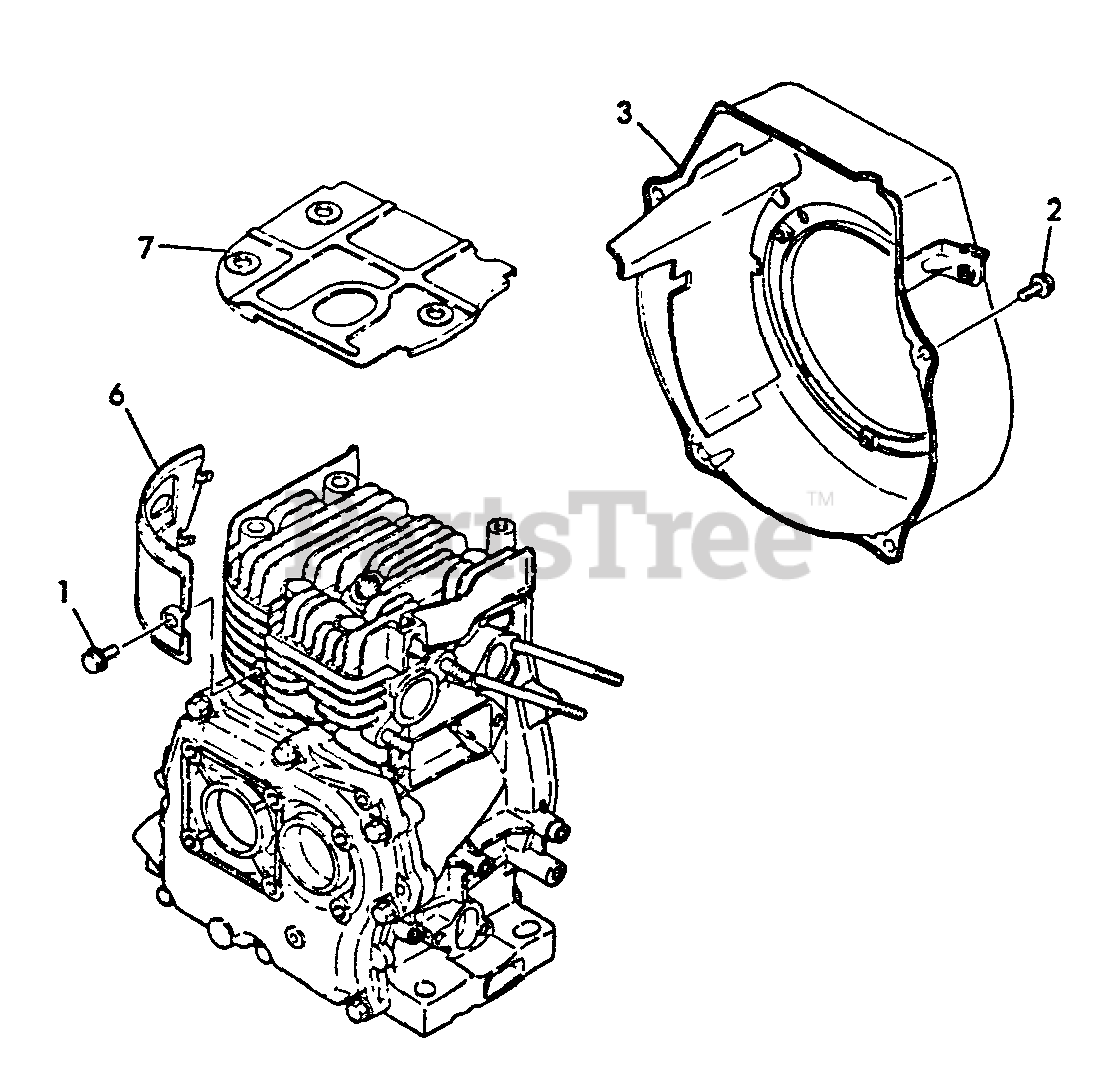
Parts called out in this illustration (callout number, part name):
1	BOLT - 6X8 -- PLATED
2	BOLT - 6X8 -- PLATED
3	COVER, FAN
6	PLATE
7	COVER, HEAD
